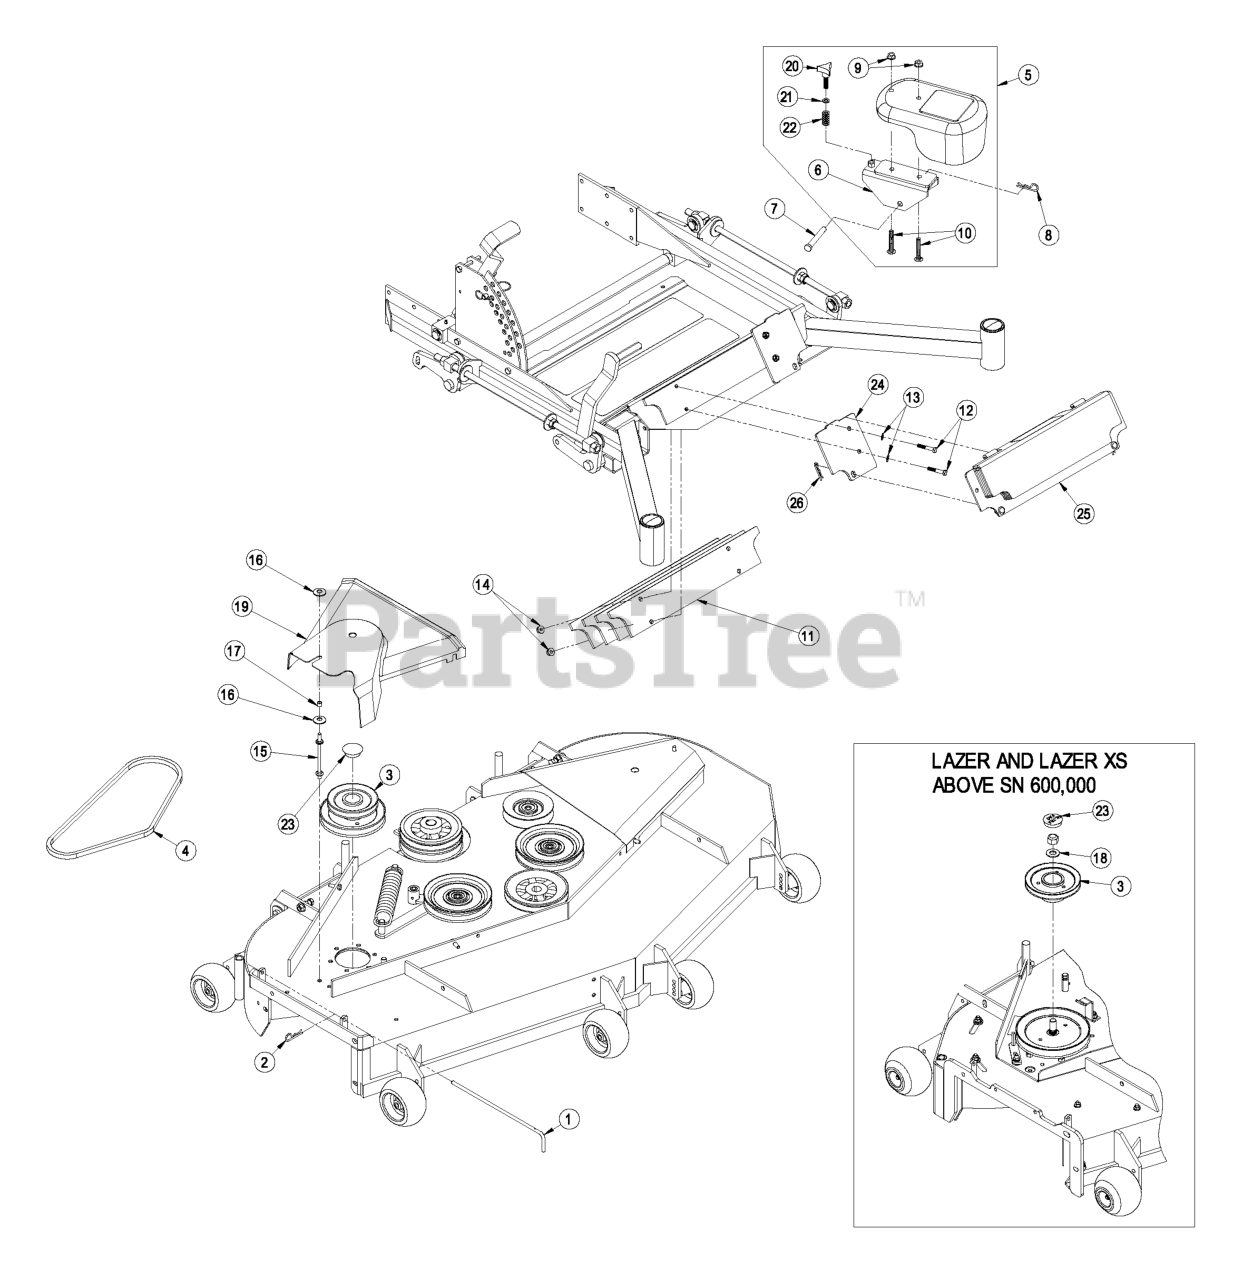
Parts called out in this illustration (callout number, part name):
1	PIN,CHUTE PIVOT
2	PIN-COTTER
3	Sheave 66 Triton
4	BELT, BLOWER DRIVE 72
5	ASM, WEIGHT 2.0" 43 POUND
6	WLD, BRACKET 2.0 ARM
7	PIN-CLEVIS
8	PIN-COTTER
9	NUT-HHF, WHIZ
10	BOLT-SQH
11	PLATE, WEIGHT
12	SCREW-HH
13	WASHER-PLAIN
14	NUT-HF
15	STUD,BELT SHIELD 4 INCH
16	WASHER-SPRING
17	SPACER
18	WASHER-FLAT
19	COVER, BELT 66
21	WASHER-FLAT
23	PLUG, BLACK NYLON 1.75
24	PLATE, WEIGHT MOUNTING
25	ASM, WEIGHT PLATE WITH DE
26	PIN-HAIR
